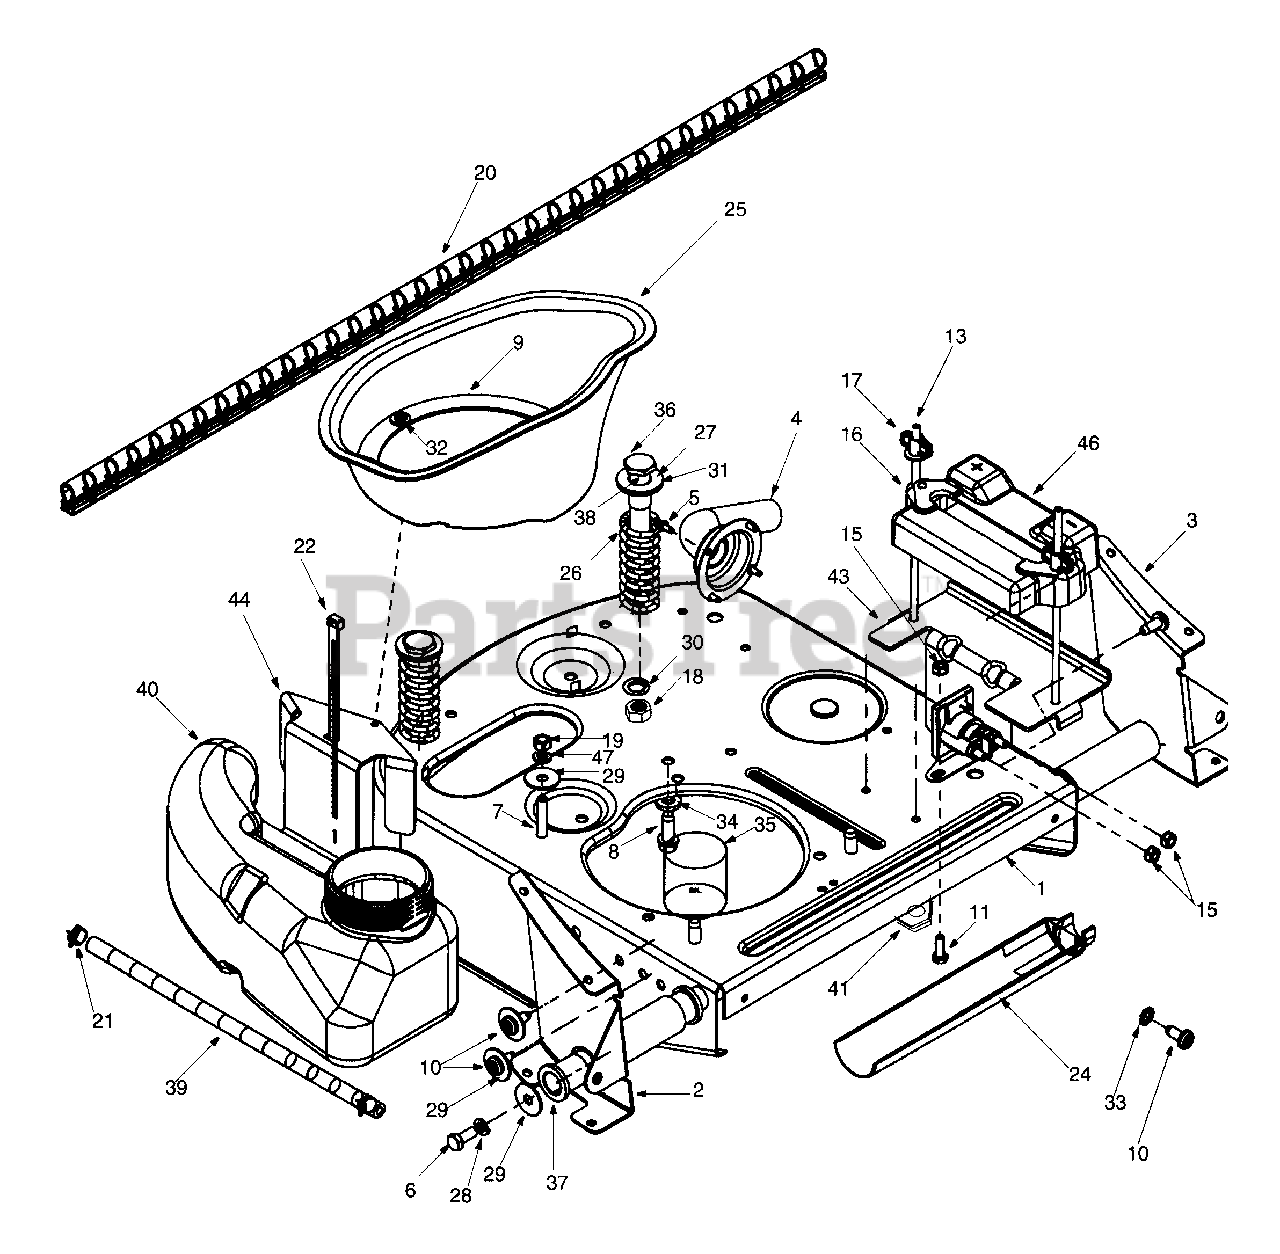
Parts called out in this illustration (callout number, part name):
5	Hex Washer Hd. TT Scr. 3/8-16 x 1.0"
6	Hex Screw 5/16-24 x 0.75"
7	Hex Hd. Scr. 5/16-24 x 1.50"
8	Hex Washer Hd. TT Scr. 3/8-16 x 1.0"
9	Sems Screw #10-32 x .62
10	Pan Hd. TL Scr. 5/16-18 x .75"
11	Hex Cap Bolt 1/4-20 x .75"
13	Battery Hold-down Rod
15	Sems Hex Nut
16	Hex Cent. Lock Nut 1/4-20
17	Wing Nut
18	Hex Nut 3/8-16
19	Hex Nut 5/16-24
20	Seal Trim
21	Hose Clamp
22	Tie Strap
24	Oil Sleeve Drain
25	Engine Duct
26	Compression Spring
27	Rubber Washer
28	Lock Washer
29	Flat Washer .344 I.D.
30	Lock Washer 3/8 I.D.
31	Flat Washer .760 I.D.
32	Flat Washer
33	Ext. Lock Washer
34	Flat Washer
36	Shoulder Screw .625 X 3.390
37	Bushing
38	Flanged Bearing
39	Fuel Line
40	Fuel Tank
46	Battery Cover
47	Lock Washer 1/4" I.D.
